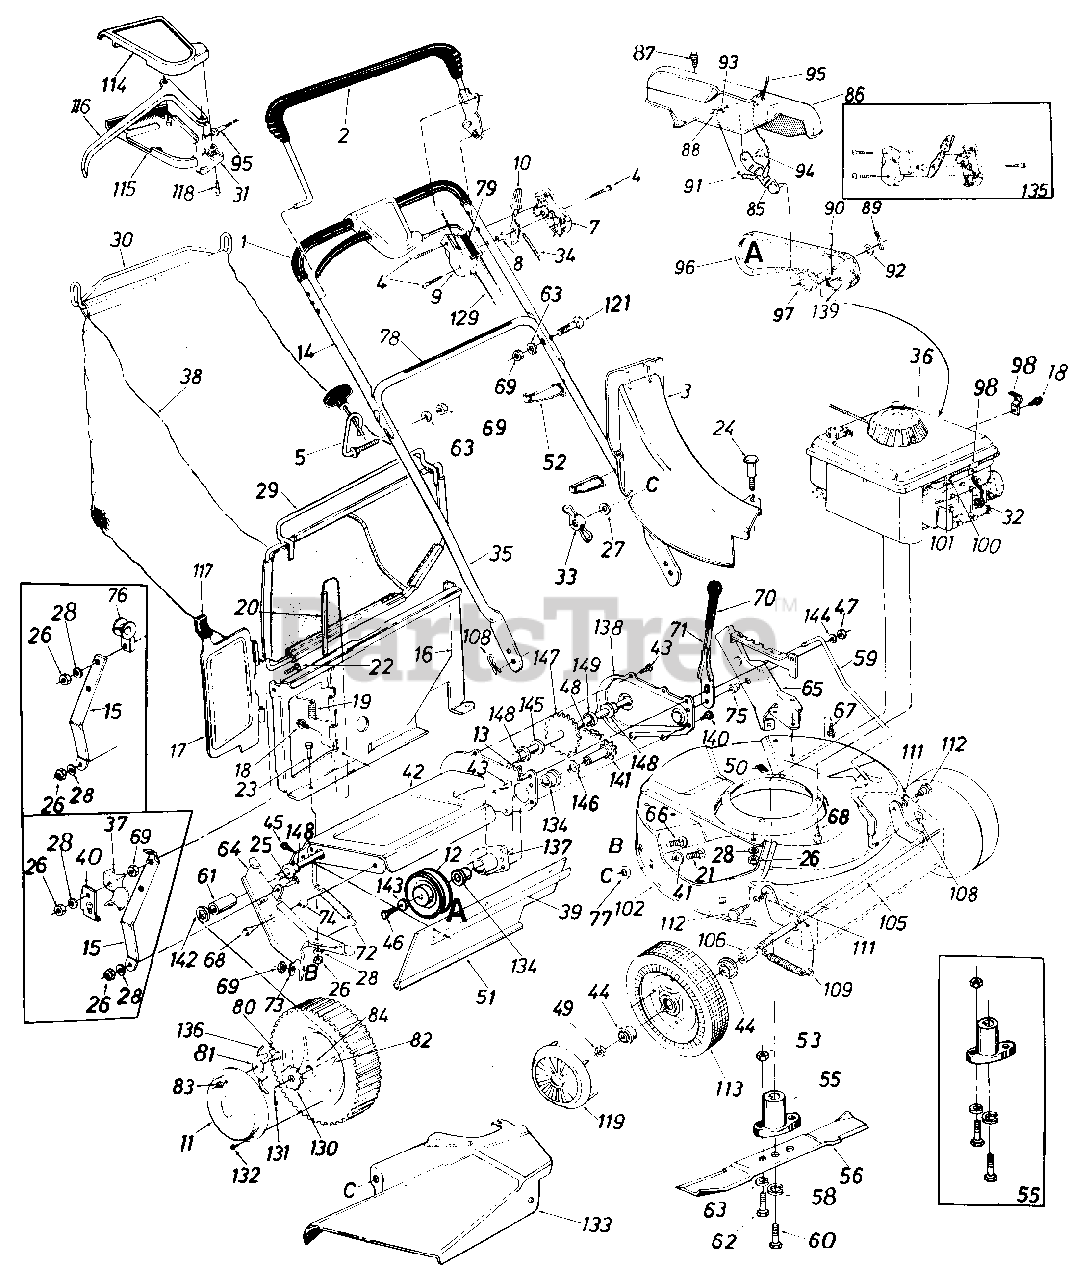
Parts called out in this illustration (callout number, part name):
2	Control Handle Ass'y.-L.H.
3	Top Discharge Chute Ass'y.
4	Truss Mach. Scr. #12 x 1.50" Lg.
5	Rope Guide Bolt
7	Control Panel Half
8	Control Disc Pin
9	Clutch Panel Half
10	Throttle Control Lever
11	Hub Cap
12	1/2" V-Pulley
13	Cotter Pin 3/32" Dia. x .75
14	Upper Handle-Chrome
15	Panel Support Brkt.
16	Top Catcher Panel
17	Top Door
18	Hex B-Tap Scr. #10 x .38"
19	Torsion Spring
20	Pivot Pin
21	Carriage Bolt 1/4-20 x .62"
22	Truss Mach. Scr. 1/4-20 x 1.0" Lg.
23	Hex Bolt 1/4-20 x .50" Lg.
24	Shoulder Bolt .312 Dia. x .18 Lg. Special
25	Hex Bolt 1/4-20 x .62" Lg.
26	Hex Nut 1/4-20 Thd.
27	Bell-Wash. 1/4" I.D.
28	L-Wash. 1/4" I.D.
29	Front Grass Catcher Frame
30	Grass Catcher Handle
31	S.P. Control Cover
32	Spark Plug Insulator
33	Wing Nut
34	Throttle Control Wire 58"
35	Lower Handle-Chrome
36	Engine
37	Rope Guide Half
38	21" Top Discharge Grass Bag
39	Retaining Strip
40	Rope Retainer Spring Clip
41	Fl-Wash. .344" I.D. x .62"
42	Chain-Axle Ass'y.
43	Hex B-Tap Scr. 1/4" x .38" Lg.
44	Flange Ball Bearing 1/2" I.D.
45	Hex AB-Tap Scr. 1/4 x .62"
46	Hex Wash. TT-Tap Scr. 1/4-20
47	Hex Patch L-Nut 3/8-24 Thd.
48	#48 Chain .500" Pitch x .30 Links
49	Hex L-Nut 1/2-20 Thd.
51	Rear Flap 3.75" x 17.30" Lg.
52	Cable Tie
53	Hex Nut 5/16-24 Thd.
55	Blade Adapter Kit
56	21" Blade
58	L-Wash. 3/8" 1 D.-H.D.
59	Heignt Adj. Rod 19.42" Lg.
60	Hex Bolt 3/8-24 x 2.25" Lg. (Grade 5)
61	Spacer .51" I.D. x .69" O.D. x.69" Lg.
62	Hex Bolt 5/16-24 x 1.00" Lg. (Grade 5)
63	L-Wash. 5/16" I.D.*
64	R.H. Handle Wheel Brkt. Ass'y.
65	L.H. Handle Wheel Brkt. Ass'y.
66	Carriage Bolt 5/16-18 x .62"*
67	Hex Wash. Hd. B-Tap Scr. 5/16-1 8
68	Hex Wash. Hd. TT-Tap Scr. 3/8-1 6
69	Hex Nut 5/16-18 Thd.*
71	Height Adj. Lever
72	Extension Spring .50" O.D. x 3.80" Lg.
73	Bell-Wash. 5/16" I.D.
74	Spacer .385" I.D. x .502" O.D. x .270" Lg.
75	Shld. Spacer .500" Dia. x .100
76	Rope Guide
77	Bolt Retainer 1/4 x .50" O.D.
78	Instruction Label
79	Control Label
80	Shld. Scr. .342" Dia. x .268
81	Pawl
82	Wheel Ass'y. Comp.-Rear 8x 1.75
83	Hex Ins. L-Nut 1/4-20 Thd.
84	Flange Ball Bearing 1/2" I.D.
85	Belt Idler Bracket Ass'y.
86	Belt Cover
87	Hex Wash. S-Tap Scr. 1/4-20 x.50" Lg.
88	Hex Nut 1/4-20 Thd.*
89	Cotter Pin 1/8" Dia. x 1.001' Lg.*
90	Spring Pin Spir. 3/16" Dia. x 1.00" Lg.
91	Extension Spring .33" O.D. x 1.12" Lg.
92	Fl-Wash. .531" I.D. x .930" O.D. x .050
93	L-Wash. 1/4" I.D.*
94	Shld. Bolt .375" Dia. x .181
95	S.P. Cable x 53.0" Lg.
96	"V"-Belt 1/2" x 32.0" Lg.
97	Fl-Idler Plastic 1.62" Dia.
98	Casing Clamp
100	Hex B-Tap Scr. #10 x .62"
101	Casing Clamp
106	Sleeve .526" I.D. x .690" O.D. x .880" Lg.
108	Intern. Cotter Pin 5/16" Dia.
109	Extension Spring .50" O.D. x 3.20" Lg.
111	Intern. L-Wash. 3/8 I.D.
112	Shld. Bolt .623" Dia. x .425
113	Front-Wheel Ass'y. Comp. 7x 1.50
114	Self-Propelled Control Cover
115	Self-Propelled Control Cover
116	Control Lever
117	Door Grip
118	Fl-"C"-Sunk Hd. Tap Scr. #10 x .75" Lg.
119	Hub Cap-Plastic
121	Curved Carr. Bolt 5/16-18 x 1.38" Lg.
129	Control Cable-43" Lg.
130	Ratchet Wheel 1.62" O.D.
131	Cotter Pin 1/8" Dia. x 1.00" Lg.*
132	Pan Hd. Tap Scr. #12 x .50"
133	Side Chute Deflector Ass'y
134	Flange Bushing
135	Kit-Control Housing Comp.
136	Spring-Nylon
137	Bearing Hub Flange Ass'y.
138	Chain Cover
139	Engine Pulley 1/2"
140	Hex Wash. S-Tap Scr. 1/4-20 x.50" Lg.
141	Sprocket-Shaft Ass'y.
142	Fl-Wash. .531" I.D. x .93" O.D.
143	Bell-Wash. .265" I.D. x .75" O.D.
144	Fl-Wash. .385" I.D. x .87" O.D.
145	Fl-Wash. .51" I.D. x 1.0" O.D.
146	Fl-Wash. .62" I.D. x 1.12" O.D.
147	Rear Shaft Ass'y. 22.05" Lg.
148	Hex Flange Bearing .506" I.D. Plastic
149	Spacer .510" I.D. x 1.00" O.D. x .210" Lg.
